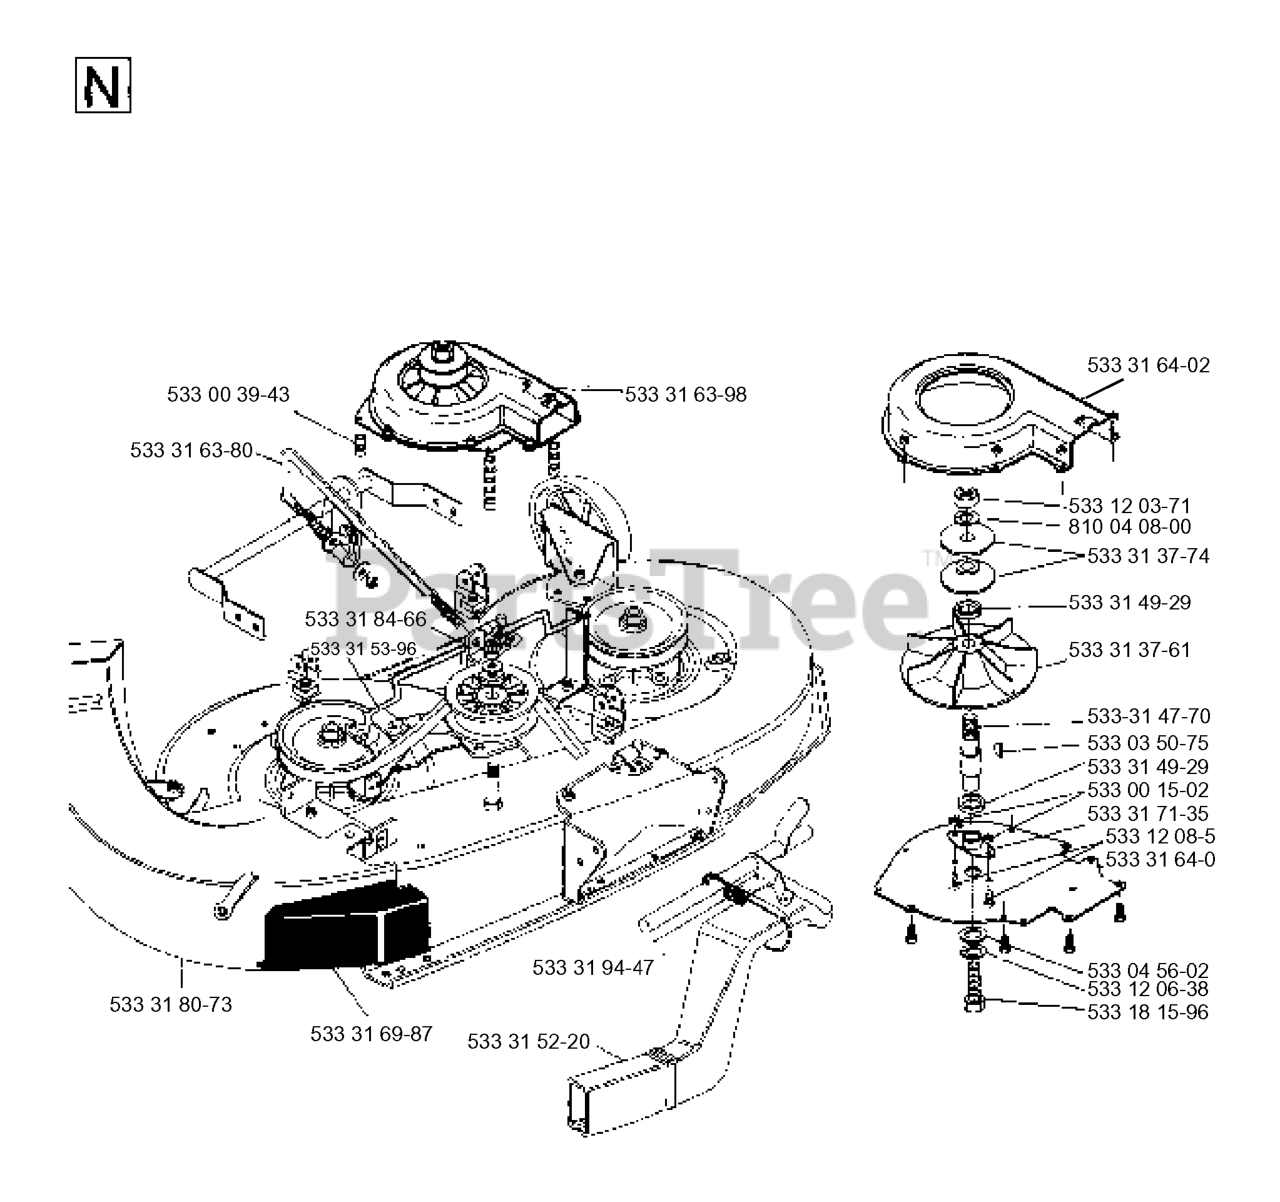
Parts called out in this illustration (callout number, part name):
1	CUTTING DECK
16	BELT GUIDE
18	NUT
20	SCREW
21	NUT
24	PULLEY
27	WASHER
28	SCREW
29	NUT
30	WASHER 3/8ä
41	NUT
43	HOLDER
44	NUT
45	NUT
53	WASHER - 15X7.3X1.6
54	NUT
56	HOLDER
57	NUT
58	NUT
72	SCREW
73	NUT
75	HOLDER
76	NUT
77	NUT
79	WASHER
86	WHEEL
88	NUT
91	PROTECTOR
107	SCREW
108	WASHER
109	NUT
110	BOLT.CARR.SQNK.5/16-18UNC.X3/4
